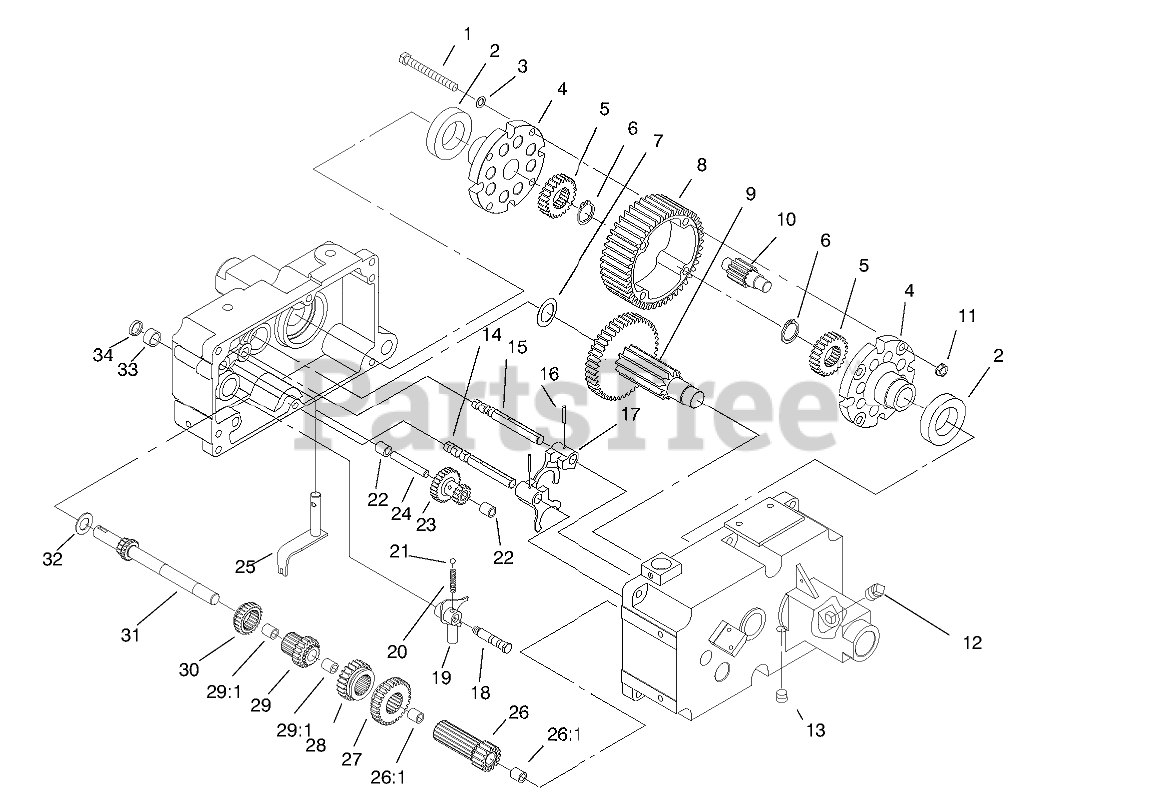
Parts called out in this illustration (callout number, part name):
1	BOLT-HEX
2	BEARING-BALL
3	WASHER
4	END CAP-DIFFERENTIAL
5	GEAR-AXLE DIFFERENTIAL
6	RING-SNAP
7	WASHER-THRUST
8	GEAR-DIFFERENTIAL RING, 43T
9	GEAR ASM
10	GEAR-PINION, 11T
12	PLUG-PIPE, SQH
14	RAIL-SHIFT
15	RAIL-REAR SHIFT
16	PIN-ROLL
17	FORK-SHIFT
18	BOLT-DETENT
19	SHIFT FORK ASM
20	SPRING-SHIFT STOP
21	BALL-DETENT
22	BEARING-NEEDLE
23	Gear
24	GEAR-SHAFT REDUCTION
25	SHIFT ASM
25:1	Shift Lever
25:2	Shaft-Lever
26	GEAR
26:1	BEARING-NEEDLE
27	GEAR-LOW AND REVERSE
28	GEAR-HI AND 2ND
29	Gear
29	GEAR
29:1	BEARING-NEEDLE
30	GEAR-SLIDING
31	SHAFT-INPUT
32	WASHER-THR
33	BEARING-NEEDLE
34	SEAL-OIL
